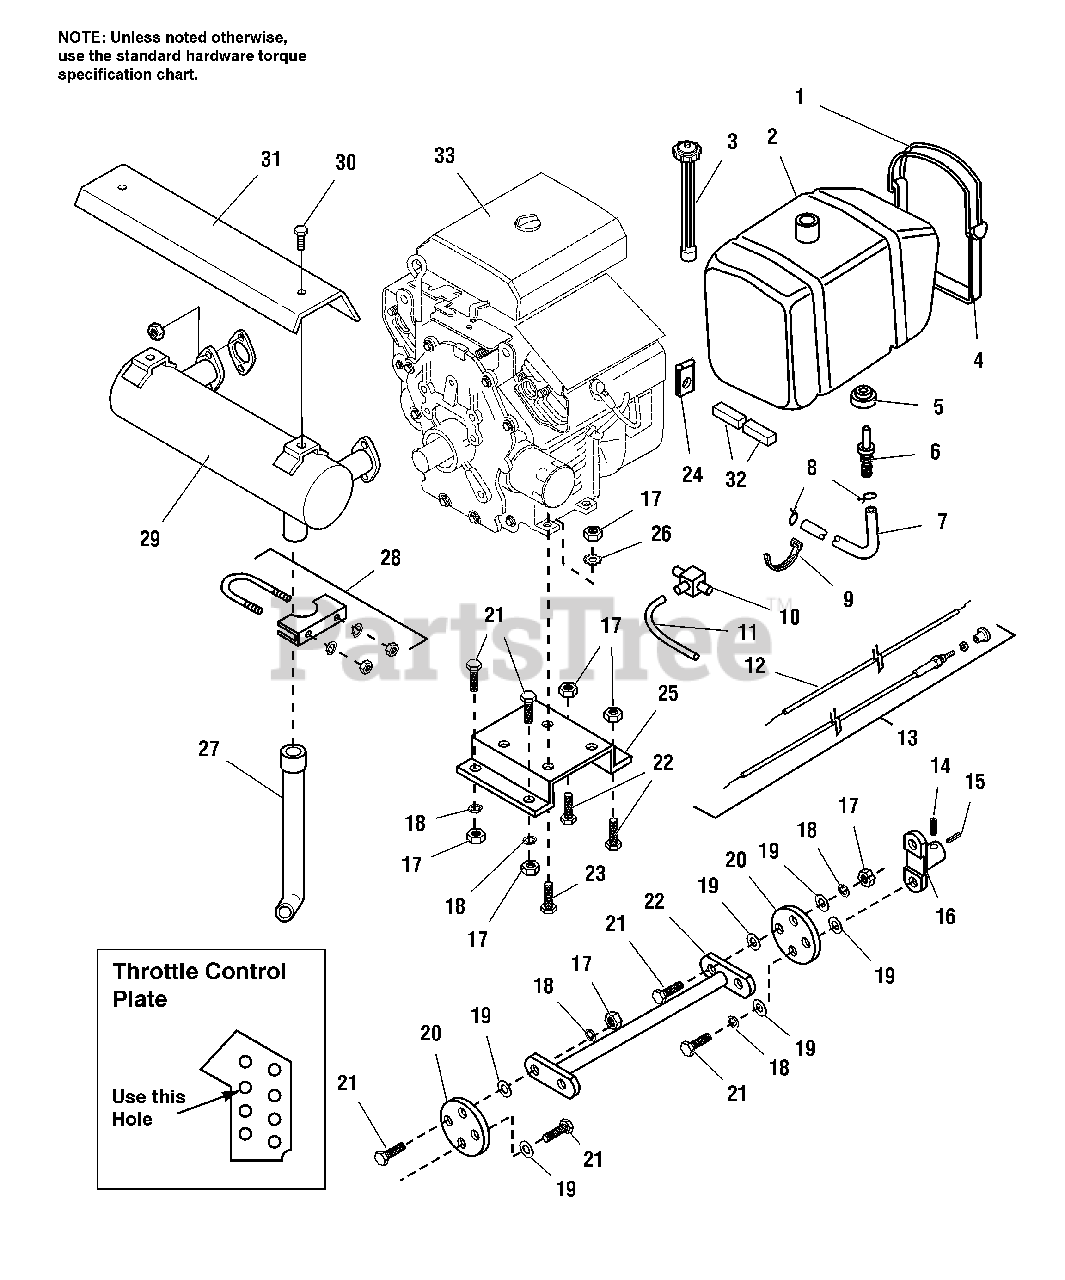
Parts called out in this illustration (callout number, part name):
1	STRAP, Rubber, Fuel Tank
2	TANK ASSEMBLY, Fuel
3	CAP, Fuel Tank
4	STRAP, Tank
7	HOSE, Fuel, 15"
8	CLAMP, Hose
9	TIE, Cable, 7.3 Lg.
10	VALVE, Shut Off
11	HOSE, Hydraulic, 1/2 ID x 3/4 x 12
12	CONTROL, Throttle
13	CONTROL, Choke
14	SETSCREW, 3/8-24 x 3/8
15	KEY, Drive Shaft, 3/16 x 1-1/4
16	FLANGE, Drive Shaft
17	NUT, Hex, Full, 3/8-16
18	LOCKWASHER, 3/8
19	WASHER
21	CAPSCREW, Hex Hd, .375-16 x 1.000
22	DRIVE SHAFT ASSEMBLY
23	CAPSCREW, Hex Washer Hd, Taptite, 3/8-16 x 1.75
25	PLATE, Engine
26	LOCKWASHER, Ext. Tooth, 3/8
27	ELBOW PIPE, Exhaust
28	CLAMP, Exhaust
29	MUFFLER, Exhaust
30	CAPSCREW, Hex Hd, Taptite, 5/16-18 x 1/2
31	HEAT SHIELD, Muffler
32	PAD, Neoprene
33	ENGINE, Kohler, 18HP OHC
